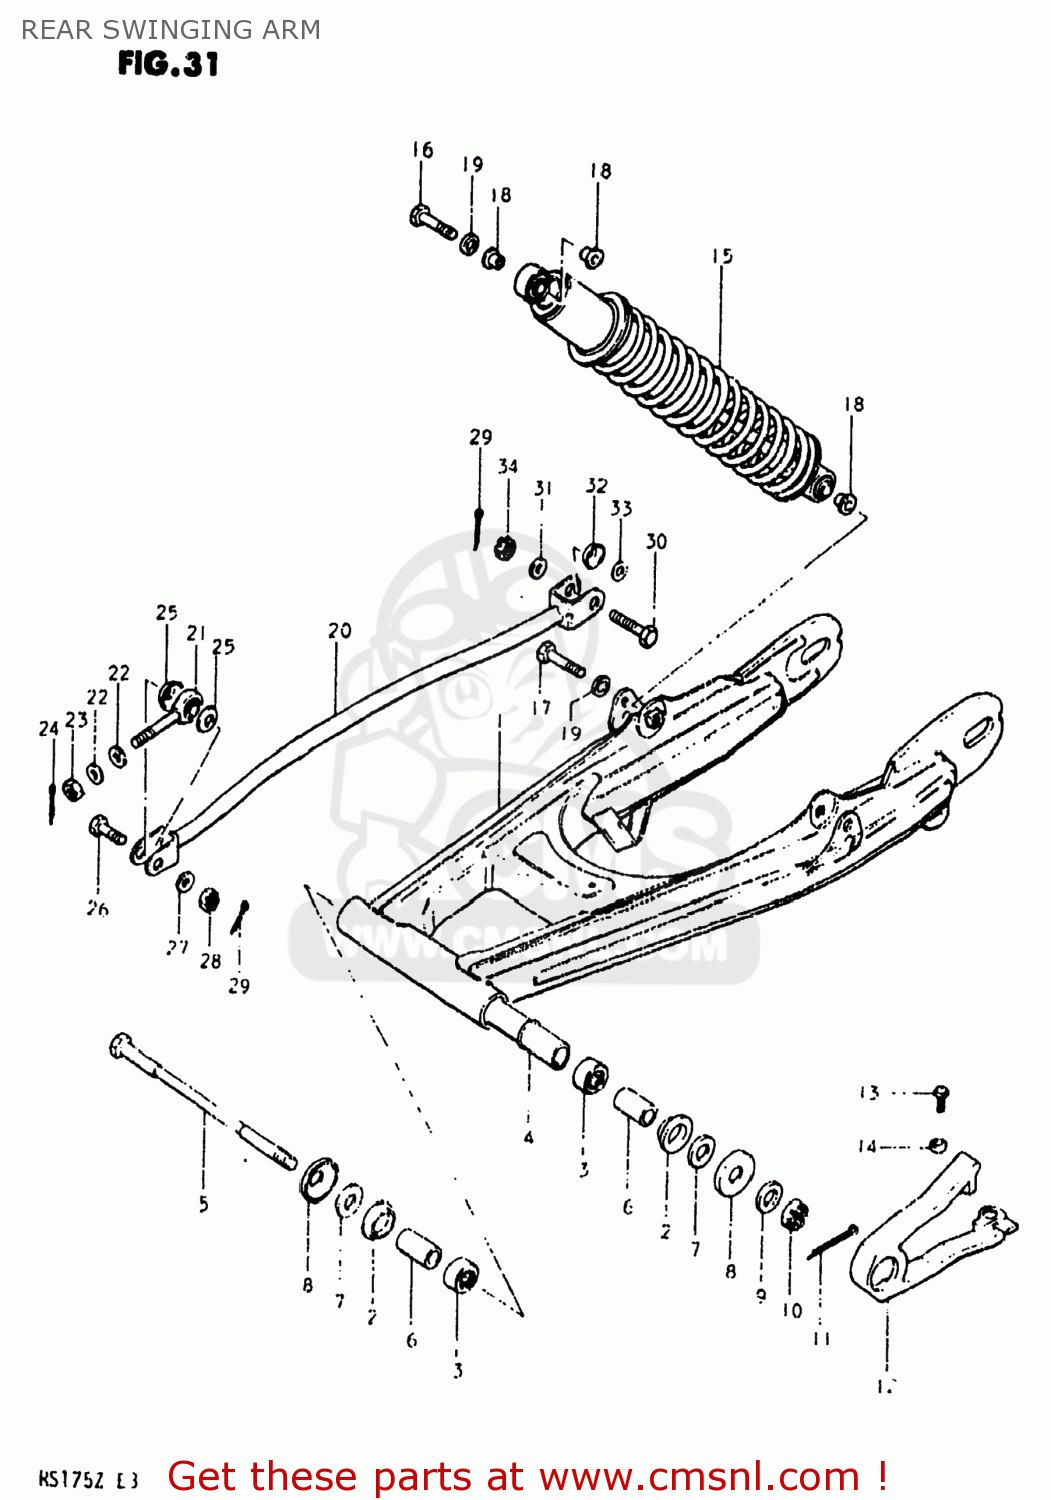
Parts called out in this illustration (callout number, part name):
1	SWING ARM ASSEMBLY,REAR
2	BUSH,RR SWINGINGARM PIVOT
3	ROLLER BEARING (17X24X2
4	SPACER
5	SHAFT,RR SWINGINGARM PIVOT
6	SPACER,RR SWGARM PIVOT
7	WASHER
8	COVER,REAR SWING ARM DUST
9	WASHER
10	NUT, REAR AXLE
11	COTTER PIN
12	BUFFER,CHAIN TOUCH DEFLECTOR
13	SCREW,CHAIN TOUCH DEFEND
14	SPACER (5.5X8X4)
15	ABSORBER ASSEMBLY,REAR SHOCK
16	BOLT
17	BOLT
18	SPACER,RR SHK ABS INNER
19	WASHER
20	TORQUE LINK,REAR
21	BEARING
22	WASHER
23	NUT
24	PIN
25	26
26	BOLT 8X28
27	WASHER
28	NUT 8MM
29	PIN 20X20
30	BOLT 8X35
31	WASHER
32	33
33	WASHER (8.5X16X2.6)
34	NUT 8MM
